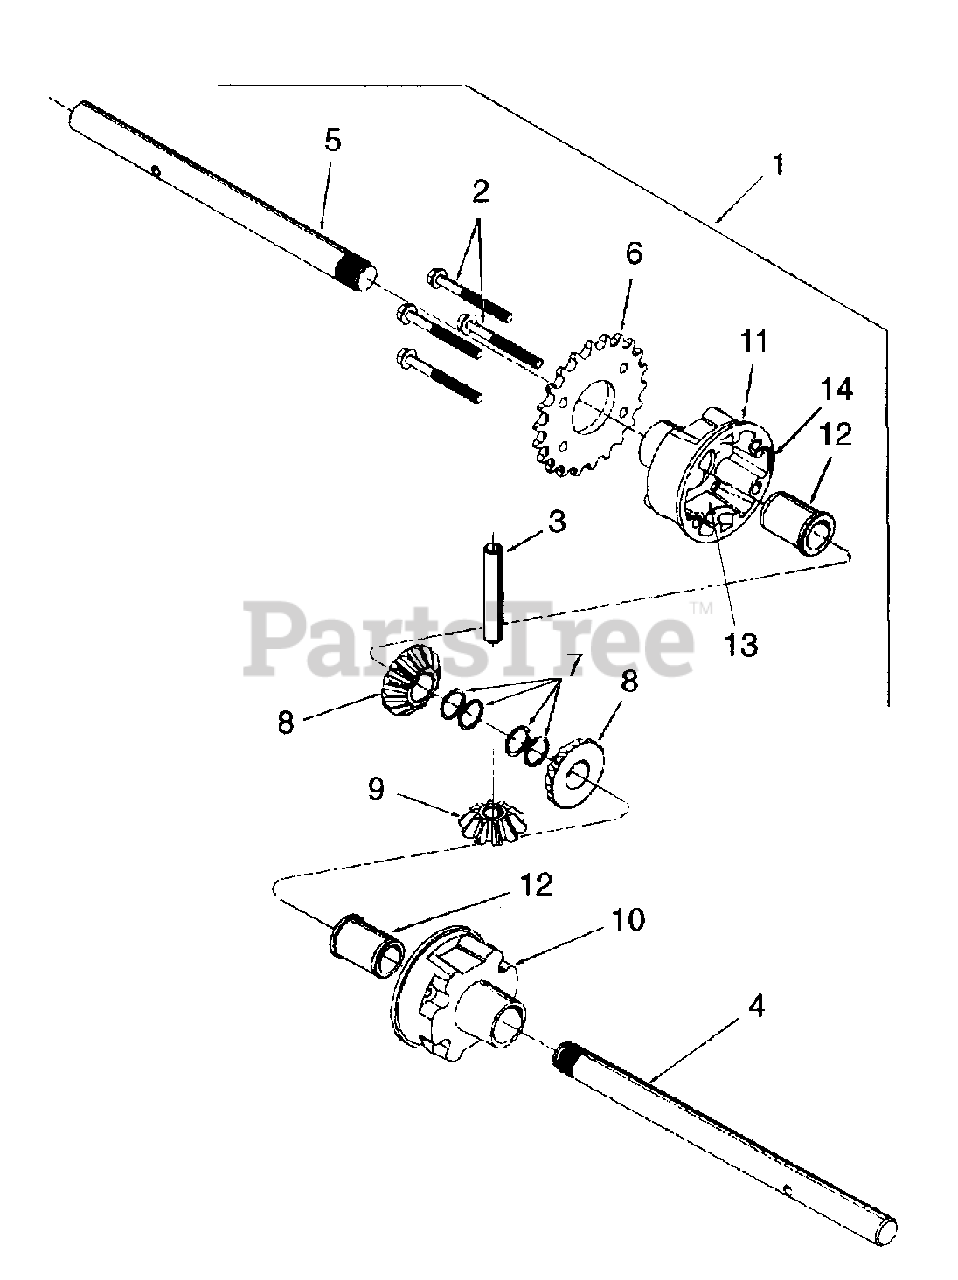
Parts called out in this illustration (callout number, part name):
1	Differential Ass'y Complete
2	Screw, Hex Wash Hd Tapp 1/4-20 x 2-5/16
3	Cross Shaft
4	Axle Shaft, .75 x 10-95
5	Axle Shaft, .75 x 9.82
6	Sprocket, 22T
7	Ring, Retaining
8	Gear, Differential, 14T
9	Gear, Differential, 10T
10	Housing, Differential RH
11	Housing, Differential LH
12	Bearing, Flange, .75 ID x 1.0 OD
13	Grease, Benalene
14	Sealant, Ultra Grey Loctite 5699
